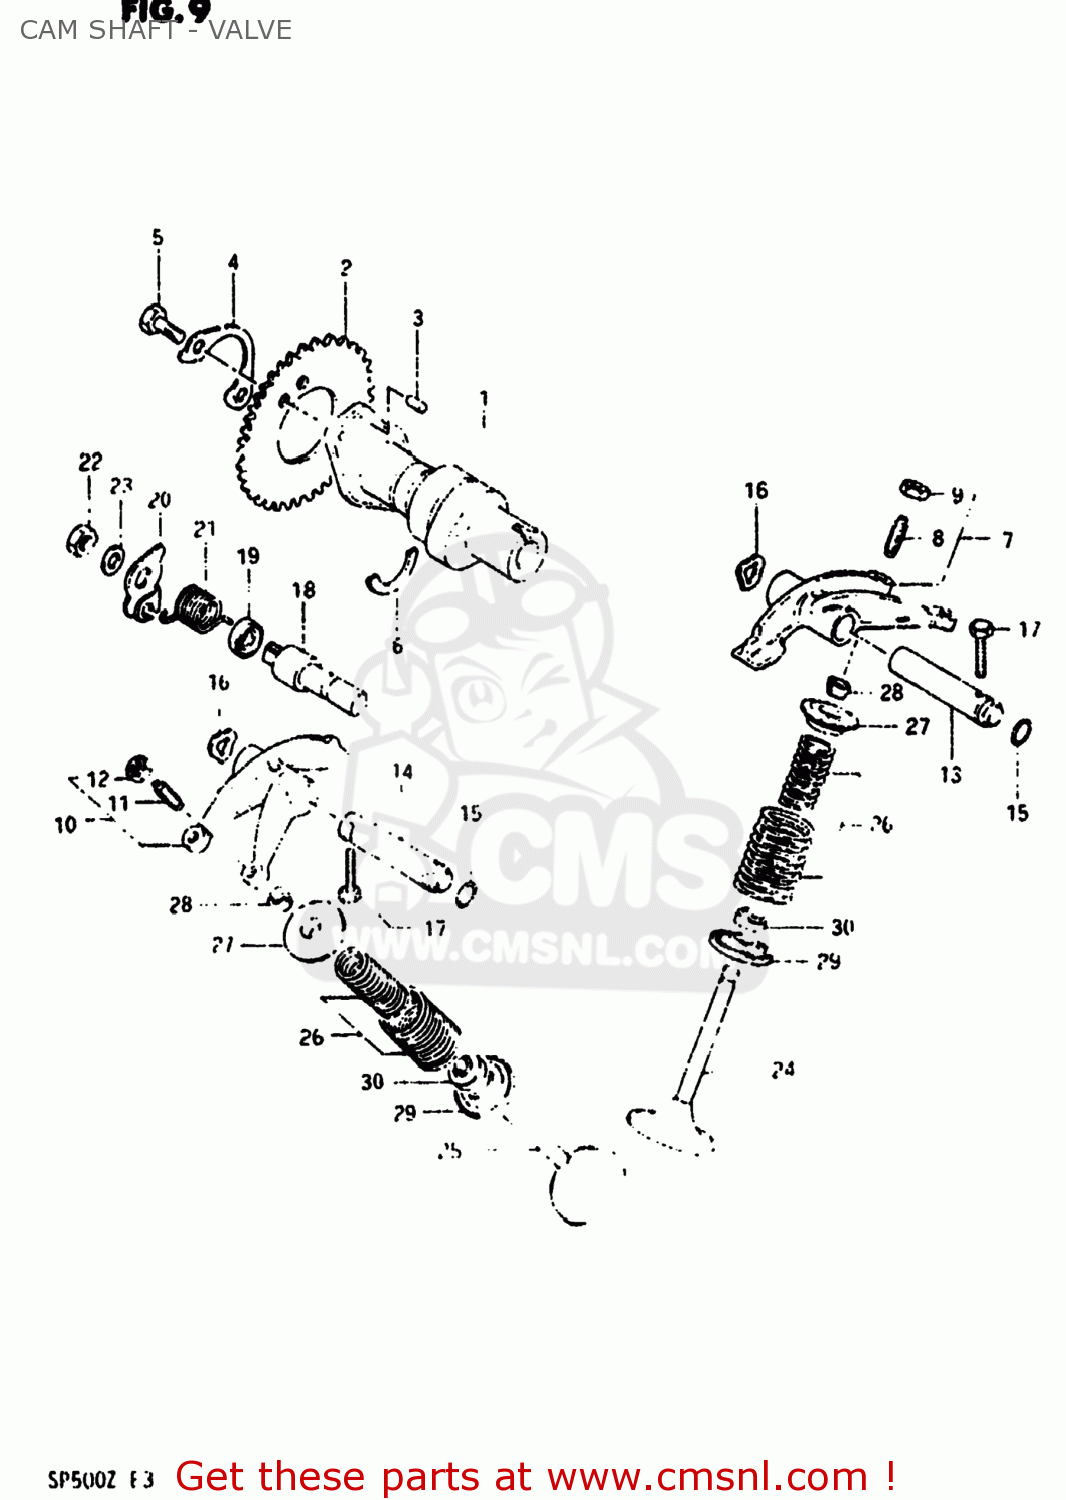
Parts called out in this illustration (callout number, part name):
1	CAMSHAFT
2	SPROCKET,CAMSHAFT(NT:42)
3	PIN
4	WASHER,CAM CHAIN SPROCKET
5	BOLT(6X12.5)
6	C RING
7	ARM,VALVE ROCKER
8	SCREW,TAPPET ADJUSTING
9	NUT,ADJUSTING SCREW
10	ARM,VALVE ROCKER,EXHAUST
11	SCREW,TAPPET ADJUSTING
12	NUT,ADJUSTING SCREW
13	SHAFT,VALVE ROCKER ARM
14	SHAFT,VALVE ROCKER ARM
15	O-RING
16	WASHER
17	BOLT(6X23)
18	SHAFT,DECOMPRESSION
19	OIL SEAL
20	LEVER,DECOMPRESSION SHAFT
21	SPRING
22	NUT 8MM
23	WASHER
24	VALVE,INTAKE
25	VALVE,EXHAUST
26	SHIM,TAPPET
27	RETAINER,VALVE SPRING
28	COTTER VALVE
29	SEAT,VALVE SPRING
30	SEAL,OIL(7X14.4X9)
